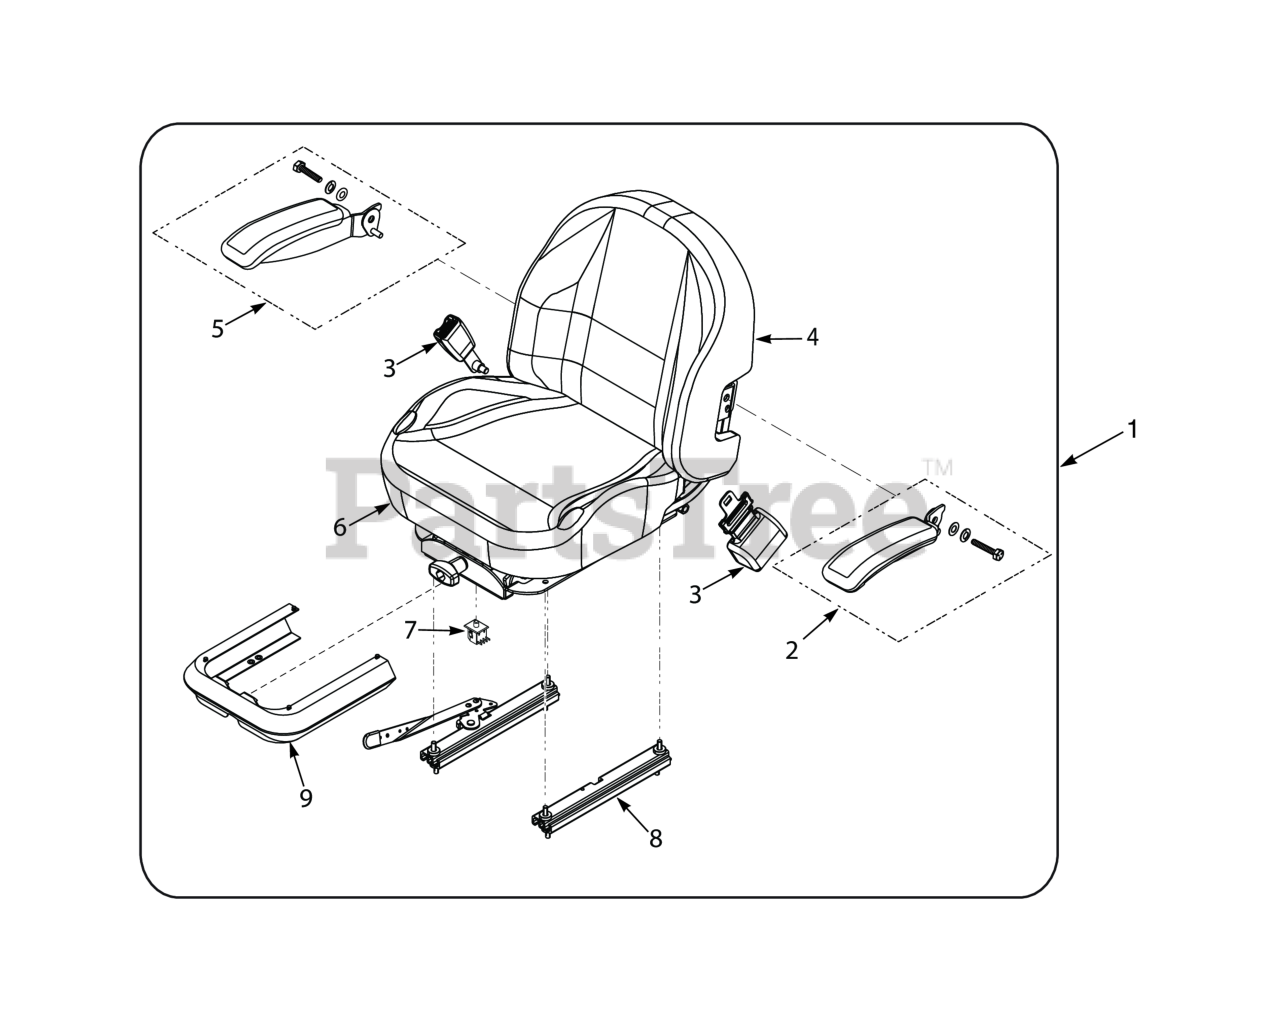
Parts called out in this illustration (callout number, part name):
1	Seat Assembly
2	Armrest Kit, LH
3	Seatbelt Kit
4	Back Cover
5	Armrest Kit, RH
6	Cushion Cover
7	Switch, Double Pole - Plunger
8	Track Set
9	Bellows, Seat
